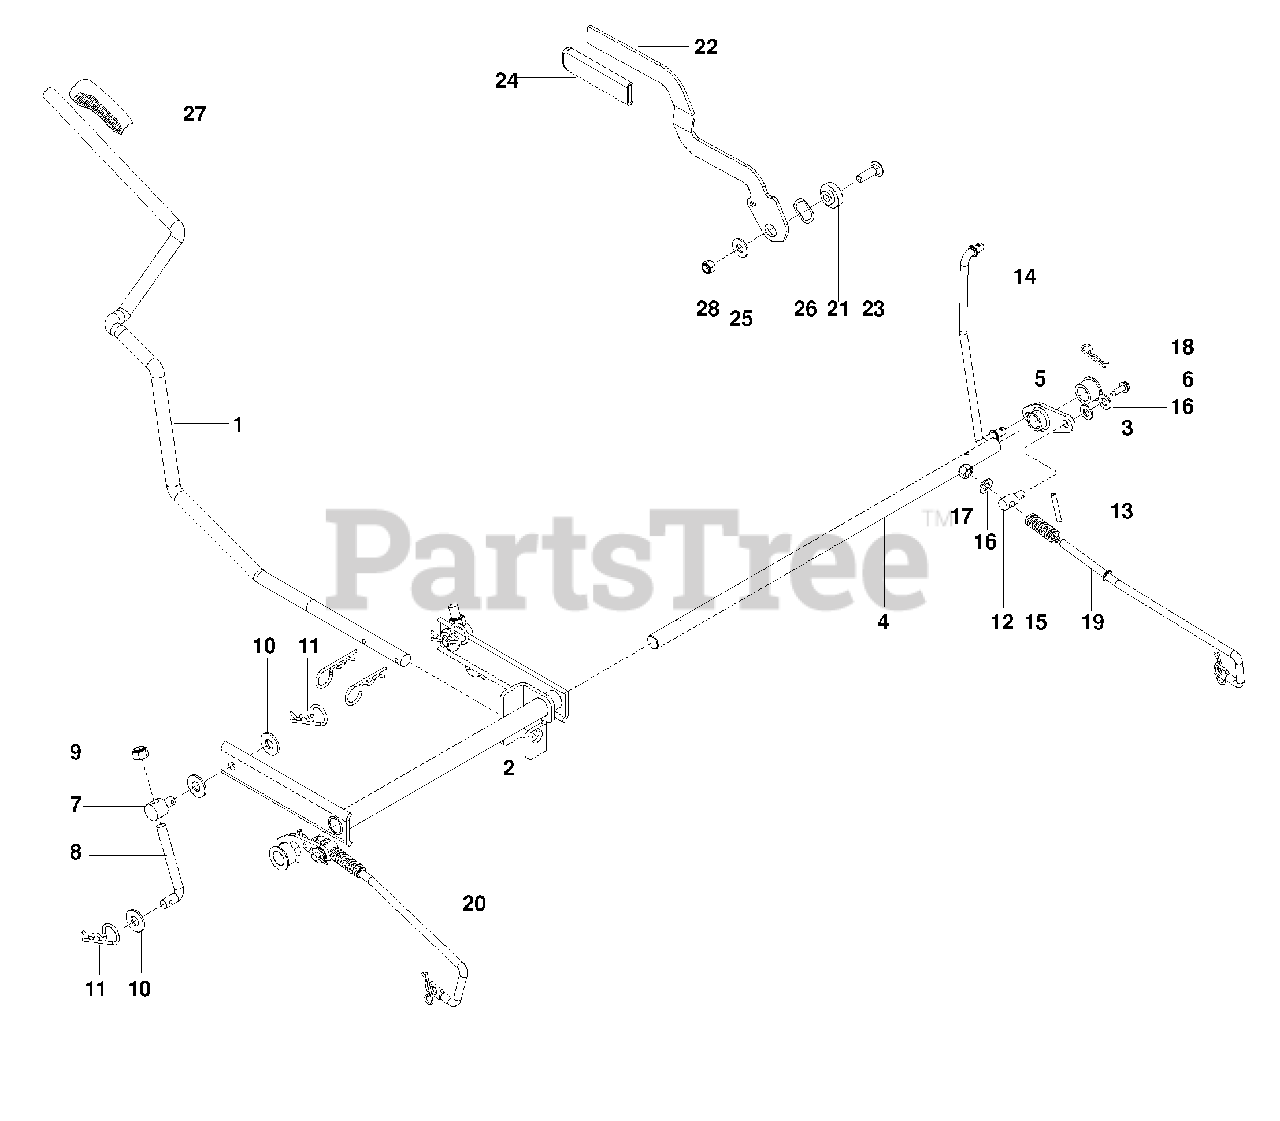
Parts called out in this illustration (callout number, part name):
1	HANDLE, LIFT
2	SHAFT, LIFT
3	BELLCRANK, BRAKE
4	ROD, BRAKE
5	BUSHING, PLASTIC
6	SCREW 10-24 x 5/8" WSH HD
8	L-ROD 31/8"
9	NUT 3/8-16 HEX NYLOC
10	WASHER 3/8 FLAT STD
12	SWIVEL, BRAKE
13	ROLL PIN 3/16"
14	LINKAGE, UPPER
16	WASHER 5/16 SAE FLAT
17	NUT 5/16-18 HEX NYLOC
18	HAIRPIN COTTER
19	LINKAGE, BRAKE RT
20	LINKAGE, BRAKE LT
21	PIVOT, BRAKE ARM
22	HANDLE, BRAKE
23	RHSNB 3/8-16 x 1 1/4
24	GRIP, BRAKE HANDLE
25	WASHER 7/16 SPRING DISK
26	WASHER, .825
27	GRIP, LIFT HANDLE
28	NUT 3/8-16 HEX JAM NYLOC
